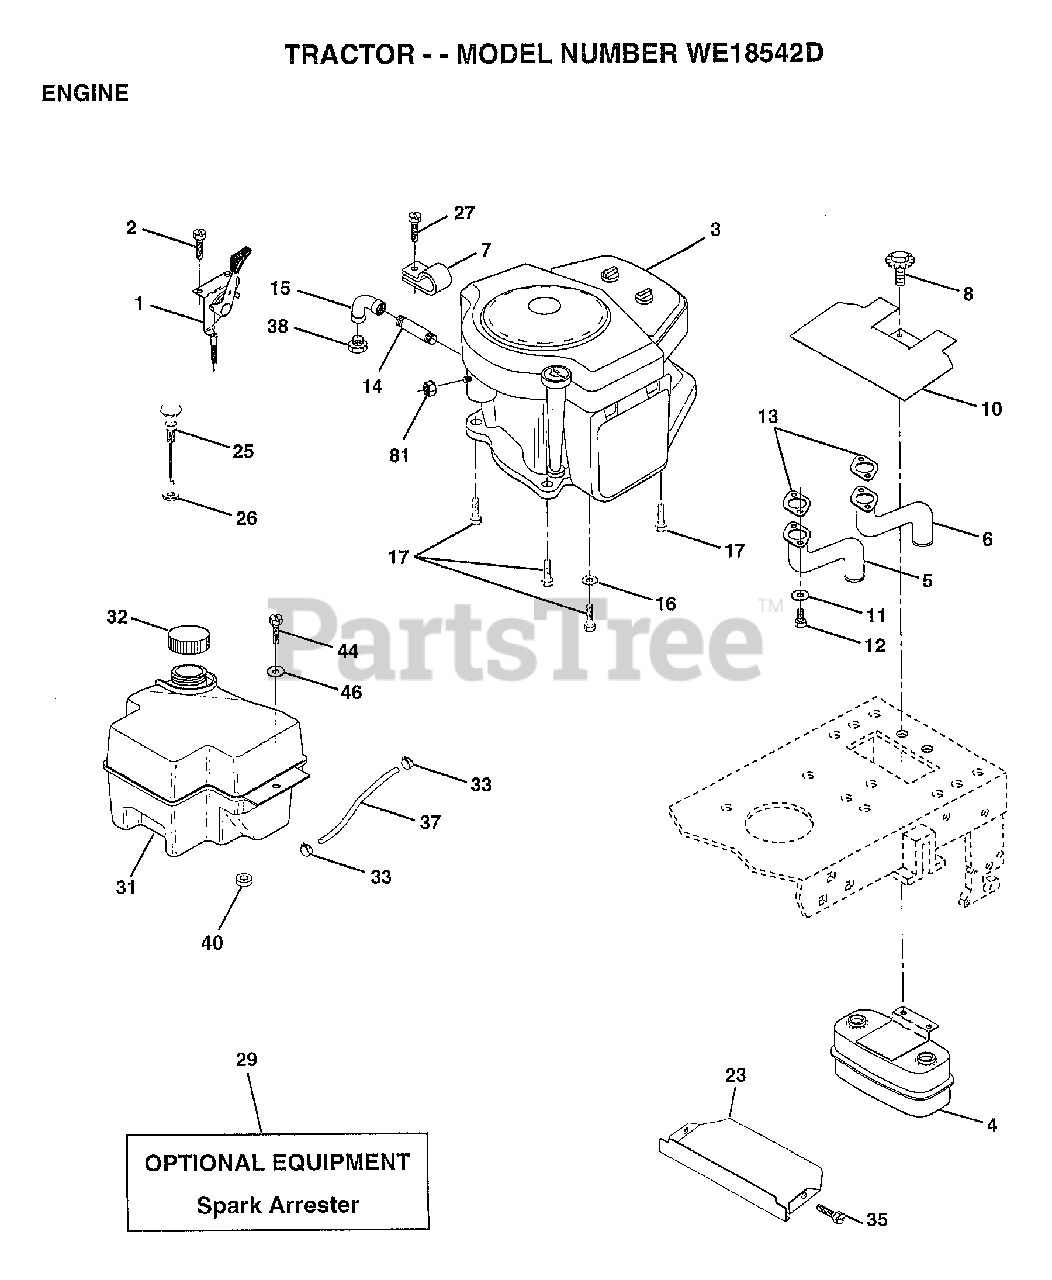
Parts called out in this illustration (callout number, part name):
1	CONTROL THRT 35.5
2	SCREW LT
4	MUFFLER.TW.LOTONE
5	EXHAUST.B&S.18.LH
6	EXHAUST.B&S.18.RH
7	CLAMP.TUBE.DBL.EN
8	BOLT.5/16-18.UNC
10	SHIELD.HEAT.
11	LOCKWASHER
13	GASKET MUFFLER
14	PIPE NIPPLE LT
15	ELBOW
16	LOCKWASHER
17	SCREW LT
23	SHIELD.BRN/DBR.GD
25	CONTROL.CHOKE.37
26	"NUT,KEPS 3/8-24IM"
27	"SCREW-TT,10-32 FL"
31	TANK.FUEL.FRONT.
32	CAP ASM FUEL
33	HOSE CLAMP
35	SCREW
37	LINE FUEL
44	SCREW HEX CRT
46	WASHER
81	NUT
